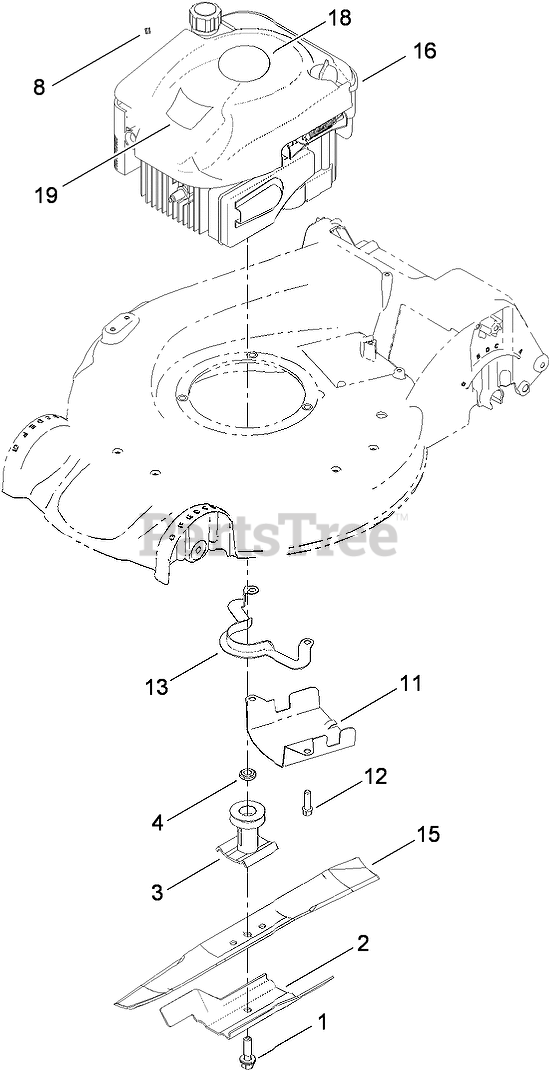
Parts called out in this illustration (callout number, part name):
1	BOLT-BLADE
2	Accelerator-Blade
3	DRIVER-BLADE
4	Spacer-Driver
8	STOP-ROPE
11	SHIELD-GRASS
12	SCREW-TAPTITE
13	GUIDE-BELT
15	BLADE-RECYCLING
18	DECAL-ENGINE
19	DECAL-RECOIL
